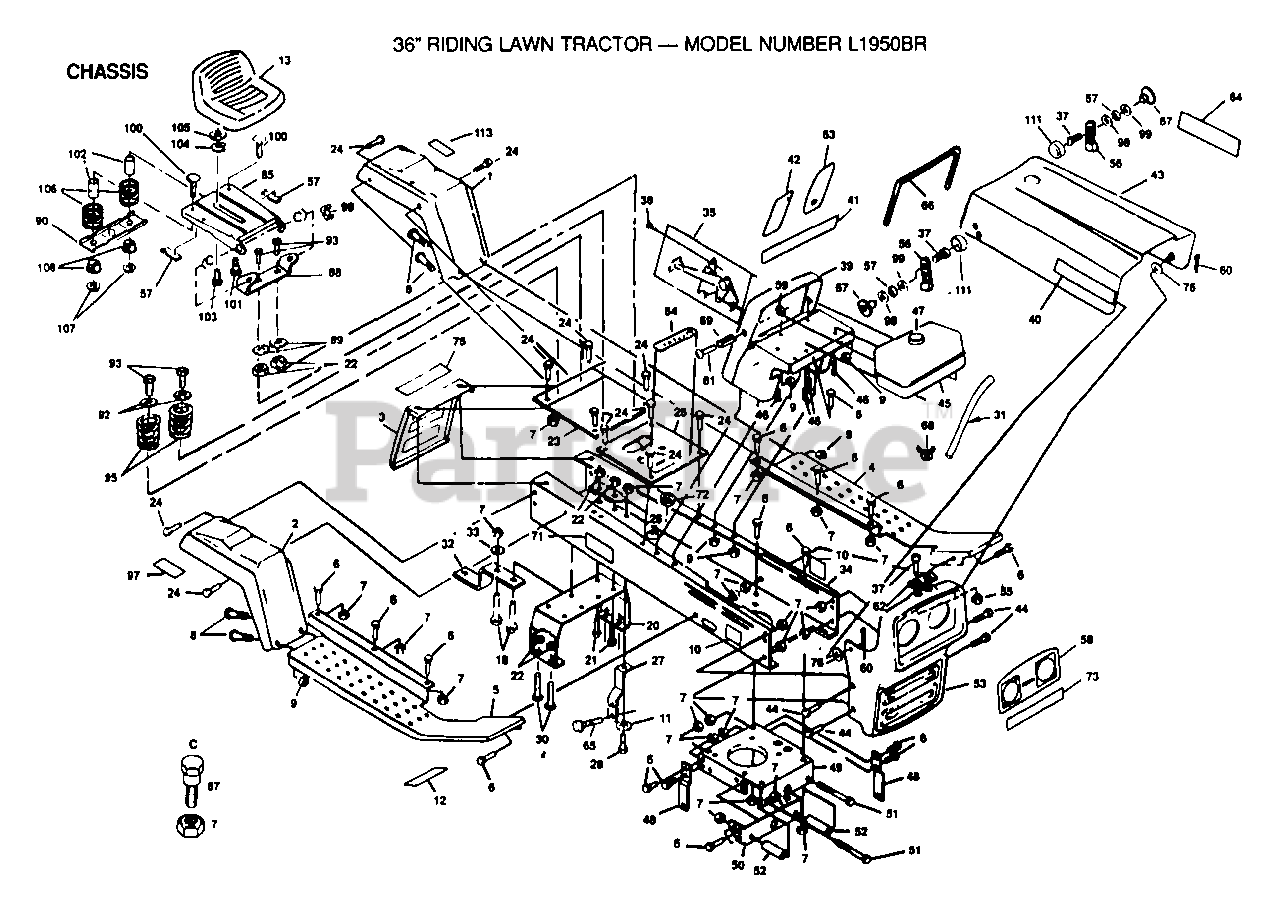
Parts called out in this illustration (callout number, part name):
3	REAR COVER T
6	BOLT
8	BOLT
11	WASHER
18	BOLT
19	GROMMET T
21	BOLT
24	SCREW LT
30	BOLT
37	SCREW
38	SCREW
45	TANK.FUEL.LT
48	BRAKE ROD BRA T
49	ENGINE BASE
50	ROCKER BAR SUPP
52	ROCKER PIVOT LT
56	HOOD LATCH T
57	STRIP FORM
61	SCREW
62	HOOD BUMPER
65	SCREW
67	WELDNUT
69	SPACER LT
76	WASHER M
77	WIRE TIE
90	BRKT SWITCH
91	SCREW
92	WASHER
93	SCREW GTV
96	SPACER T
100	BOLT
101	BOLT T
102	SPACER SPLIT
103	BOLT
104	LOCKWASHER
105	WASHER
106	SPRING
107	NUT T
108	BUSHING
